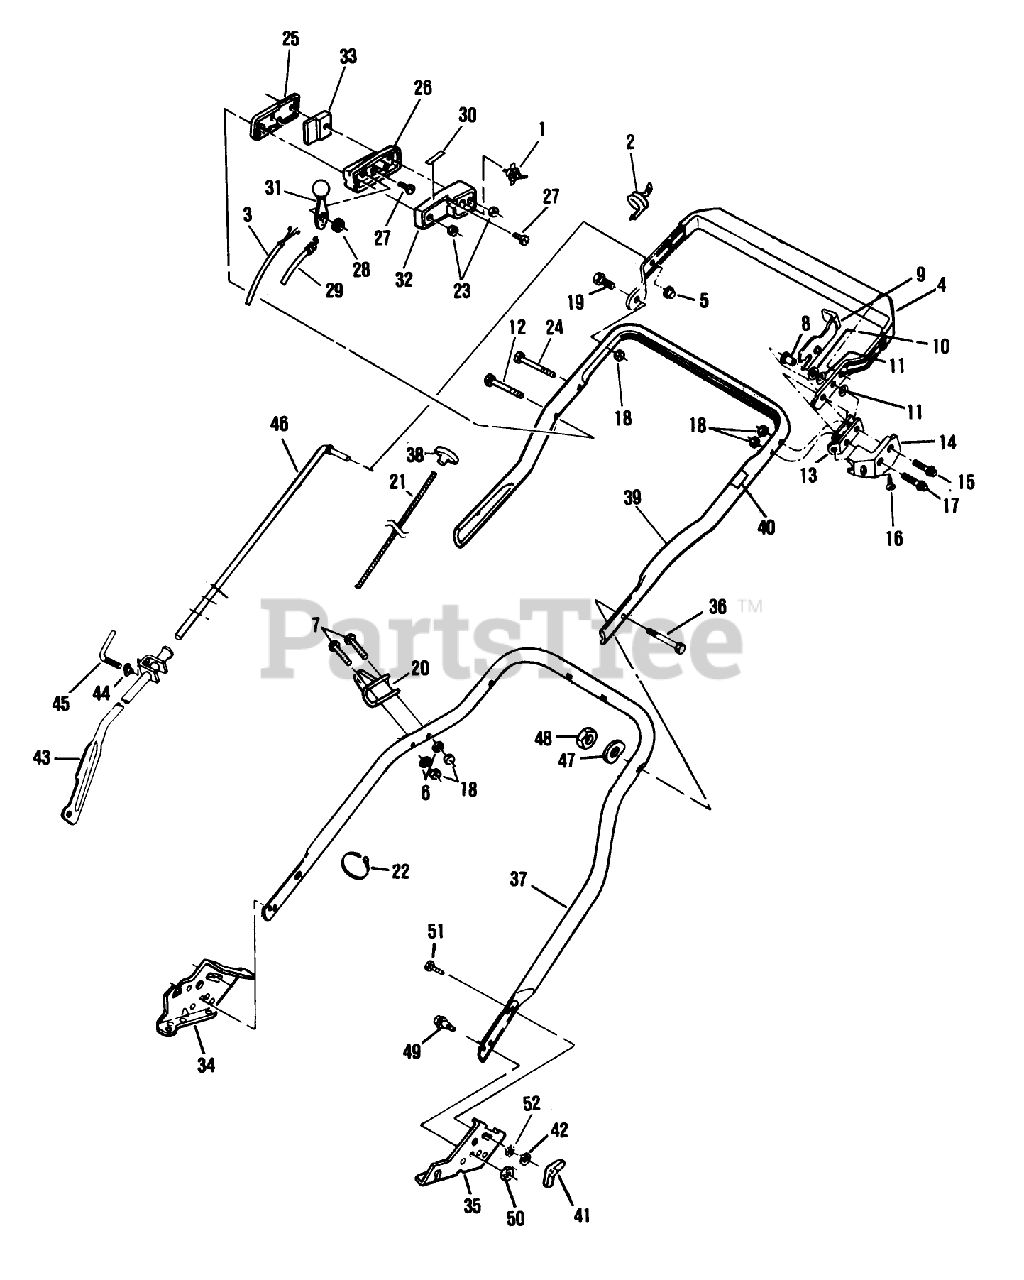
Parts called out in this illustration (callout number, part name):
6	WASHER
8	SPACER
10	WASHER M
12	SCREW
13	DOWN STOP
15	BOLT SHOU
16	SCREW F
17	SCREW
18	LOCKNUT E
19	BOLT
23	NUT C/LOCK E
25	OUTER CONTROL CASE
27	SCREW
28	WASHER-SPRING
29	CABLE THROT WES
31	LEVER&KNOB AY WES
41	NUT-WING
42	WASHER
43	CONTROL LEVER AY
46	CONTROL ROD
47	WASHER-CURVED
48	NUT-LOCK F
49	BOLT
50	NUT-JAM, LOCKING
52	LOCK WASHER LARSON
